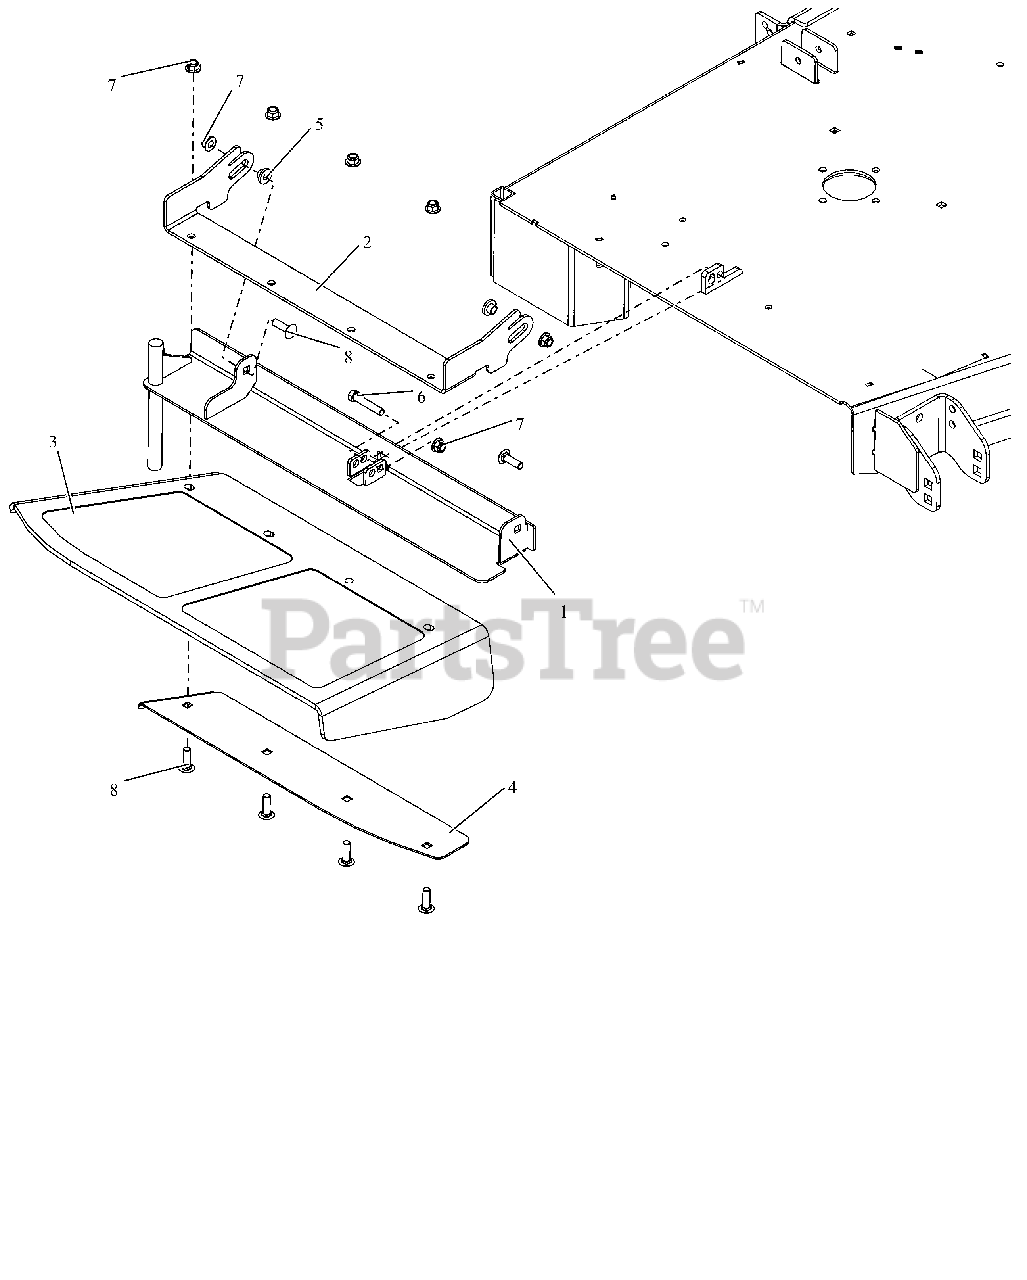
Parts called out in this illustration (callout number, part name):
1	72"DISCH CHUTE MTG WMT W/SAFE
2	72" CHUTE MTG BRKT - RED
3	CHUTE, 72" FORMED RUBBER DISCH
4	72" DISCH CHUTE CLAMP PLT -RED
5	BSHG-FLG .385X.500X.875X.406
6	BLT,HEX .38-16X2.00 G5 ZCC
7	NUT,NYL-FLG .38-16 GF ZCC
8	BLT,RHSSN .38-16X1.25 G5 ZCC
